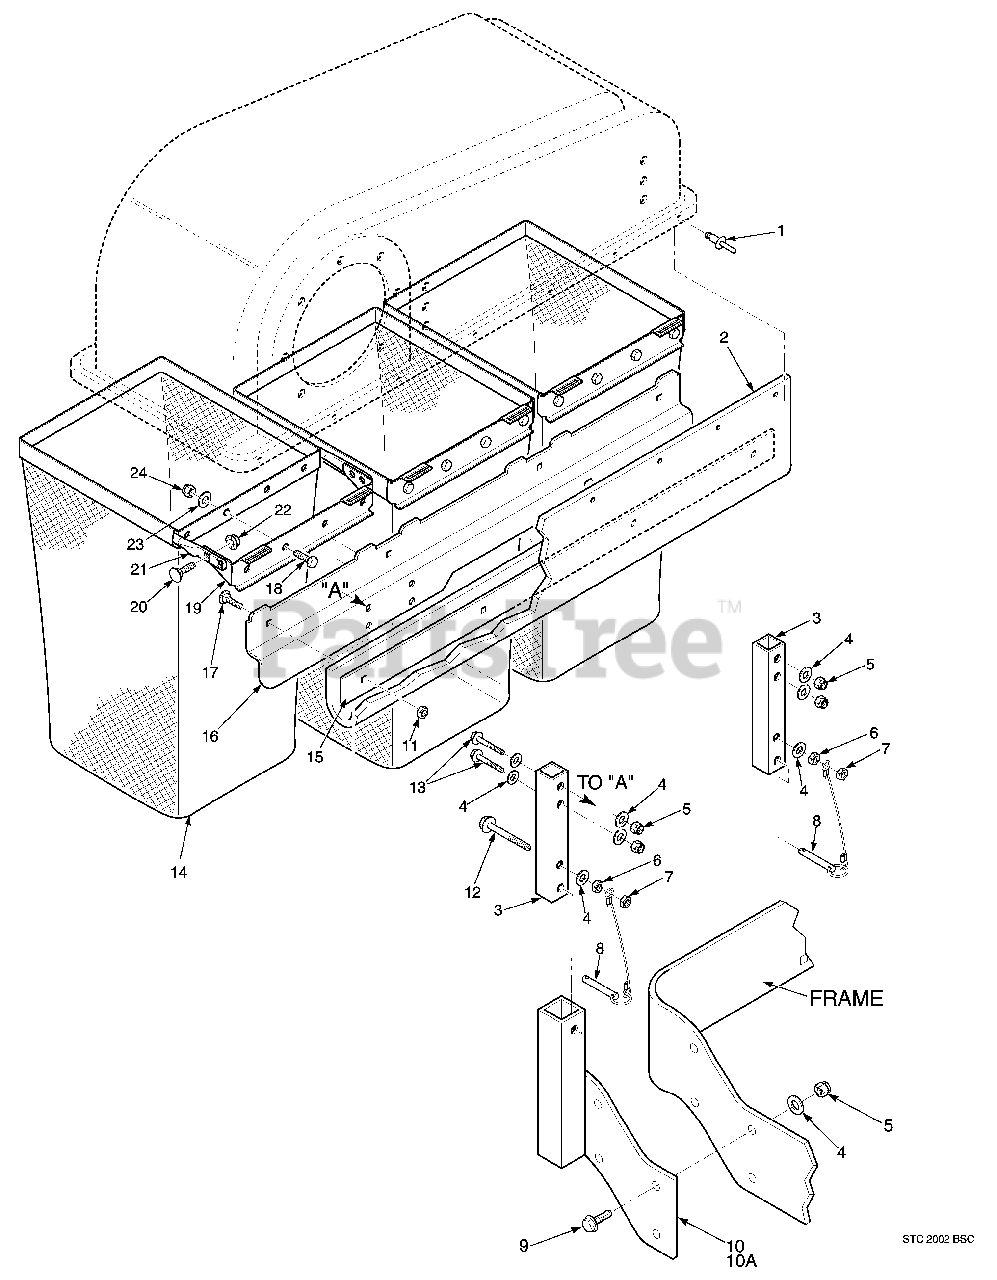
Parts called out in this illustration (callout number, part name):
1	Pop Rivet, 3/16 x .652
2	Seal, Hood
3	Tube, Upright
4	Flatwasher, 3/8-.391 x .938 x .105
5	Nut, Elastic Stop 3/8-16
6	Nut, 3/8-16
7	Hex Lock Nut, 3/8-16
8	Pin, Ring 1/2 x 2-1/4"
9	Bolt, Hex Head 3/8-16 x 1"
10	Mounting Bracket Weldment R.H
10A	Mounting Bracket Weldment L.H.
11	Lock Nut, 1/4-20 Center
12	Bolt, Hex Head 3/8-16 x 2-1/4"
13	Bolt, Hex Head 3/8-16 x 2-1/2"
14	Bag Assembly, GC-STC
15	Retainer, Seal
16	Support, Bag Frame
17	Bolt, Carr. 1/4-20 x 3/4"
18	Bolt, Hex Head 5/16-18 x 3/4"
19	Mount, Bag Frame Tube
20	Bolt, Carr. 5/16-18 x 3/4"
21	Tube, Bag Support
22	Nut, Serr. Flange 5/16-18
23	Flatwasher, 5/16-.375 x .875 x .083
24	Nut, Elastic Stop 5/16-18
